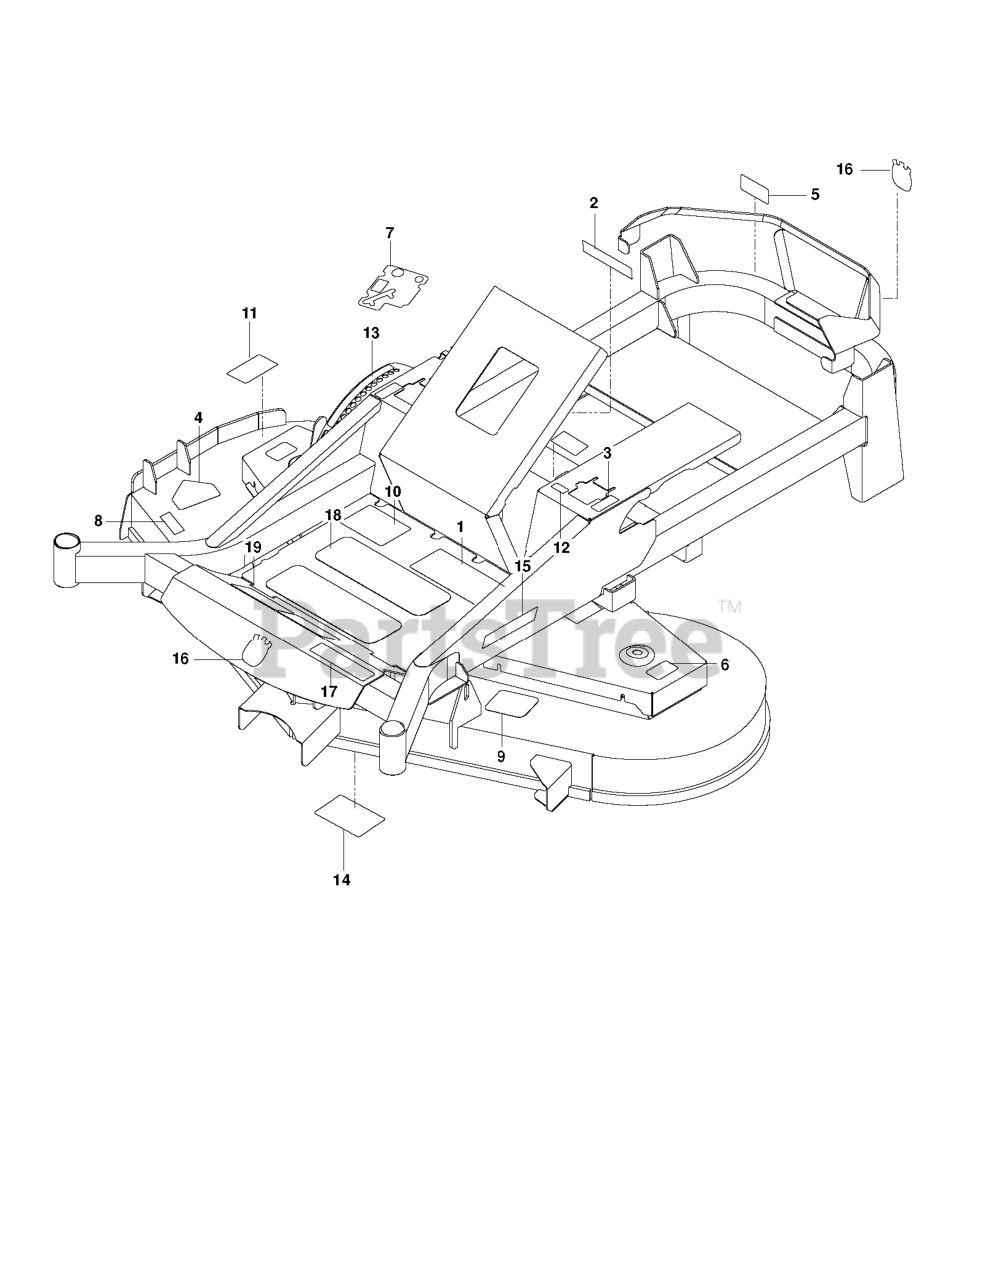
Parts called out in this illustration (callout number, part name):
1	DECAL, WARNING
2	EURO DECAL-BATTERY WARNIN6
3	DECAL, MOTION CONTROL
4	DECAL, CPSC
5	DECAL, BELT DRIVE
6	DECAL.DECK.6MIL.EURO.NOSTEP
7	DECAL, CONSOLE HUS
8	DECAL, EURO SEVERING
9	DECAL, BELT ROUTING
10	DECAL, WARNING
11	DECAL.DECK.6MIL./DEF.SHLD.WARN
12	DECAL, F.S.T.
13	DECAL, HEIGHT ADJUST
14	DECAL, SERVICE
15	RP.DECAL.BADGE.170MM.TEXTLOGO
16	DECAL.AUGER.HUSQ.CROWN.SNOW
17	DECAL.MZ52LE.HUSQ
18	ANTI-SKID PAD
